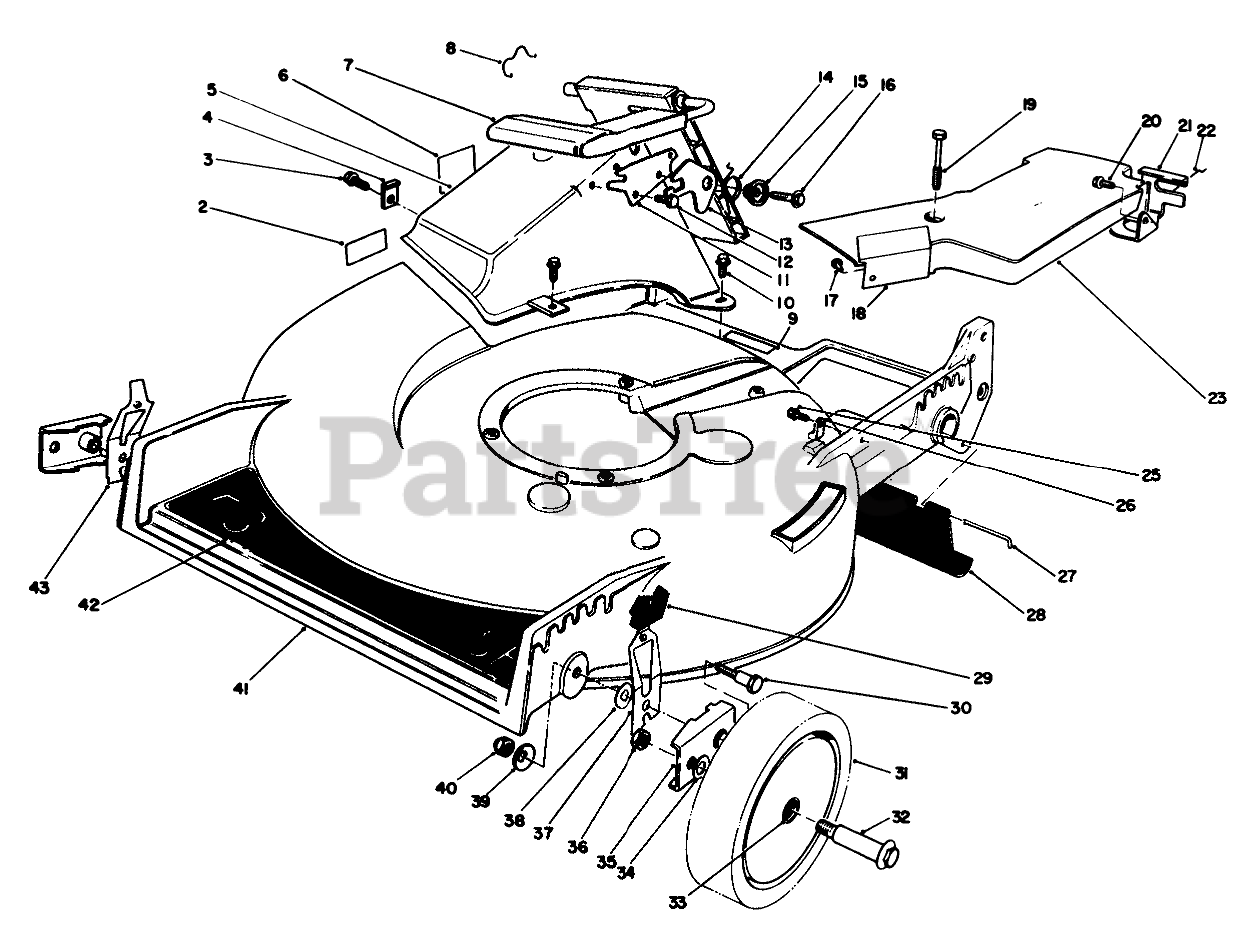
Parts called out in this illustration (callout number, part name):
2	Decal Danger
3	SCREW
4	TUNNEL CLIP
5	Tunnel Discharge
6	DECAL - DANGER
7	Discharge Door Assembly
8	DOOR RET SPRING
9	Decal
10	SCREW-HWH
11	DOOR LATCH PLATE
12	SCREW-PLASTITE
13	SAFETY LATCH
14	TORSION SPRING
15	DOOR SPACER
16	SCREW-HWH
17	RIVET-HEAD, FLAT
18	HEAT SHIELD
19	SCREW-HHFTF
20	SCREW-HWHTF
21	Bracket-Traction Adj.
22	RETAINER-CABLE
23	Belt Cover Assembly (Incl.Ref. #17 & 18)
25	SCREW
26	CLAMP-CABLE
27	ROD-SHIELD
28	SHIELD-TRAILING
29	KNOB-ARM
30	PIVOT SCREW
31	Wheel & Tire Assembly (Incl. Ref. #33)
32	BOLT-WHEEL
33	BUSHING
34	WASHER
35	HP PIVOT ARM ASM
36	Nut
37	L. HP SPRING ARM ASM
38	WASHER-PIVOT
39	WASHER-BELLEVILLE
40	NUT-LOCK, NI
41	Housing (Incl. Ref. #1)
42	DECAL - 53 SP DECK
43	R HP SPRING ARM ASM
